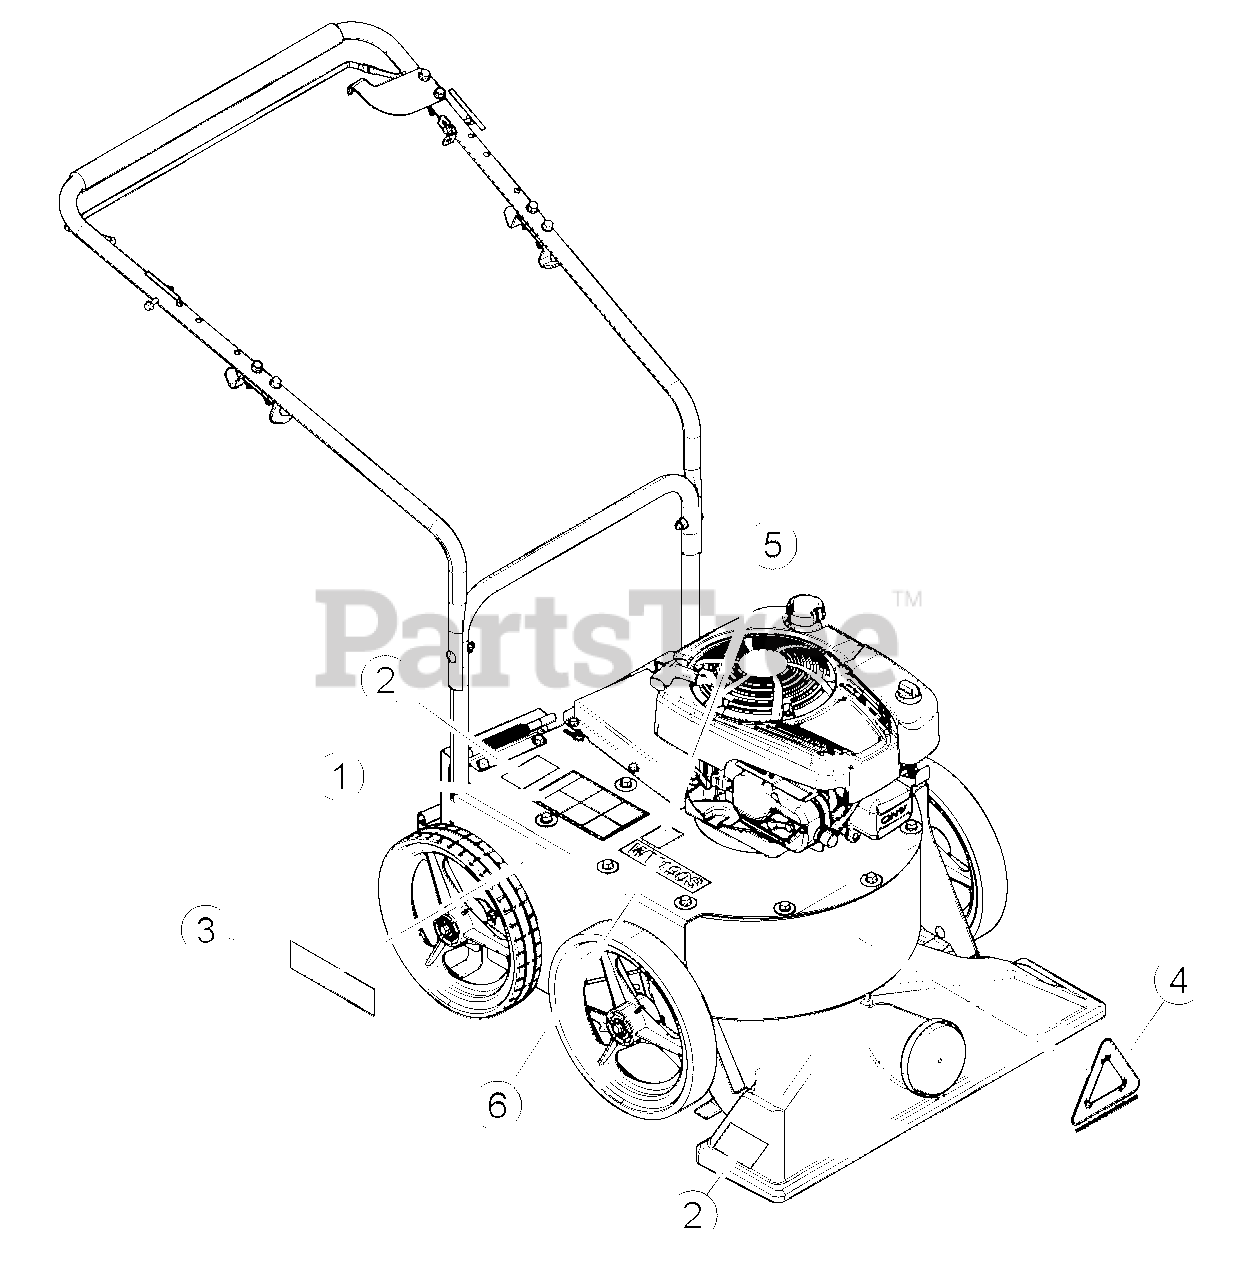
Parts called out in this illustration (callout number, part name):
1	DECAL, OPERTATING INSTRUCTIONS ISO
2	DECAL, DANGER
3	DECAL, ECHO BEARCAT
4	DECAL, COLLECT IT (WHITE)
5	DECAL, QR CODE
6	DECAL, MODEL WV160S
